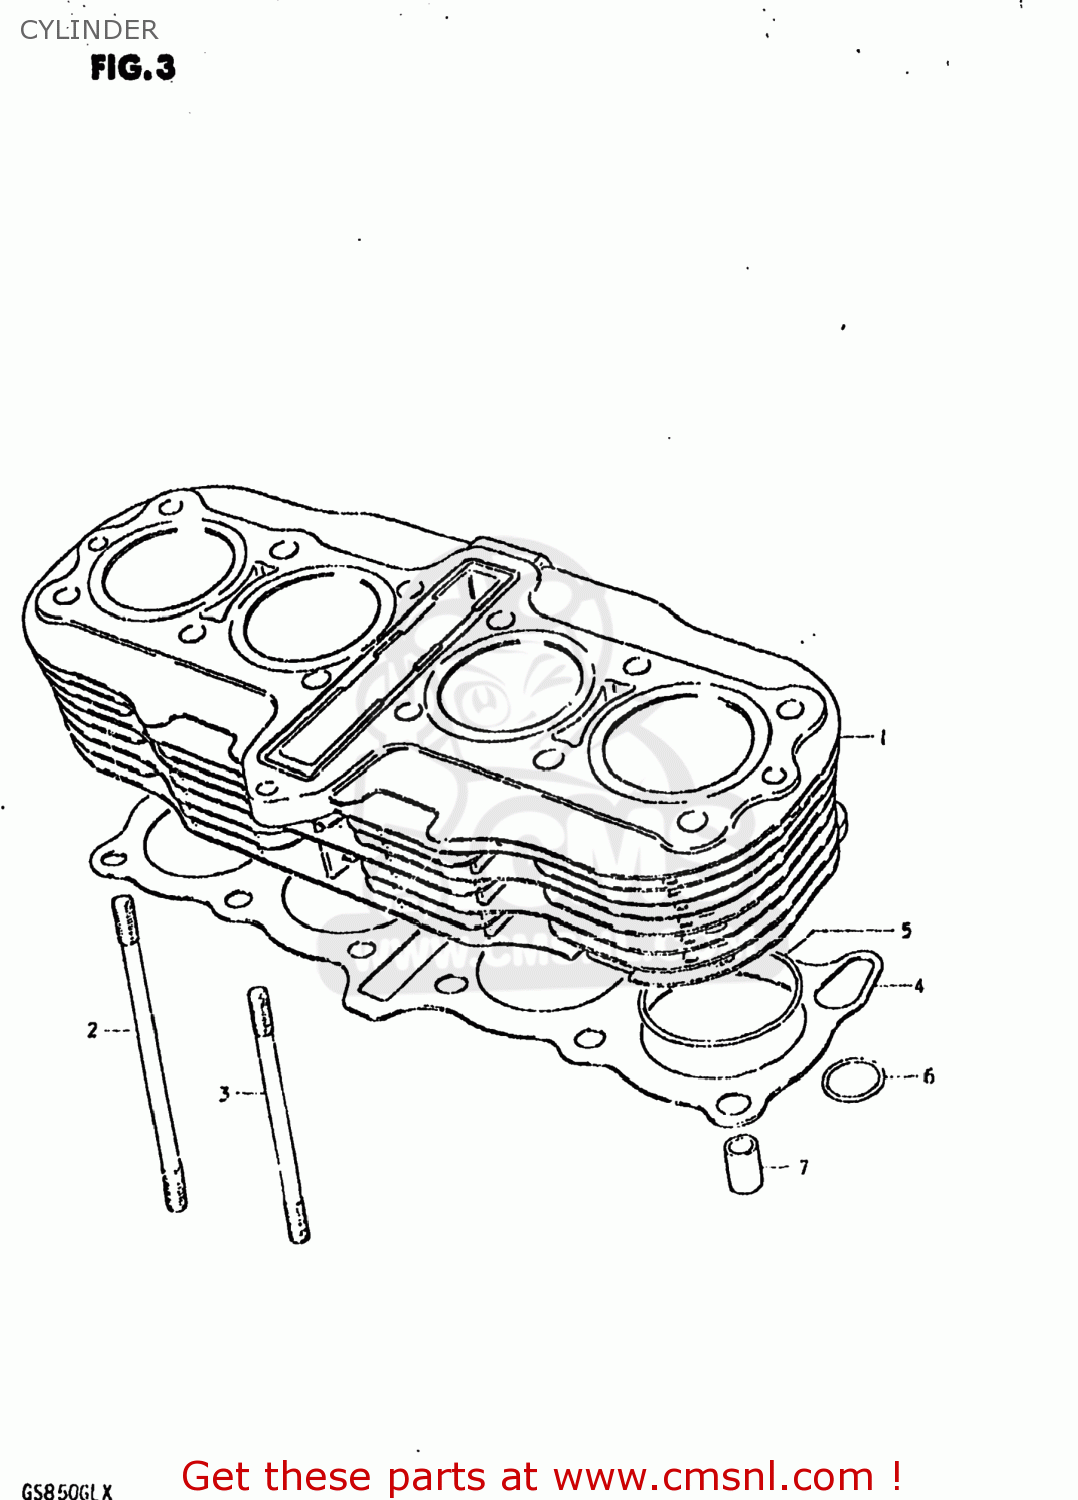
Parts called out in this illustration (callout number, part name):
1	CYLINDER
2	BOLT,STUD
3	STUD
4	GASKET,CYLINDER (MCA)
5	O RING(D:2,ID:70)
6	O RING(D:3.05)
7	PIN
